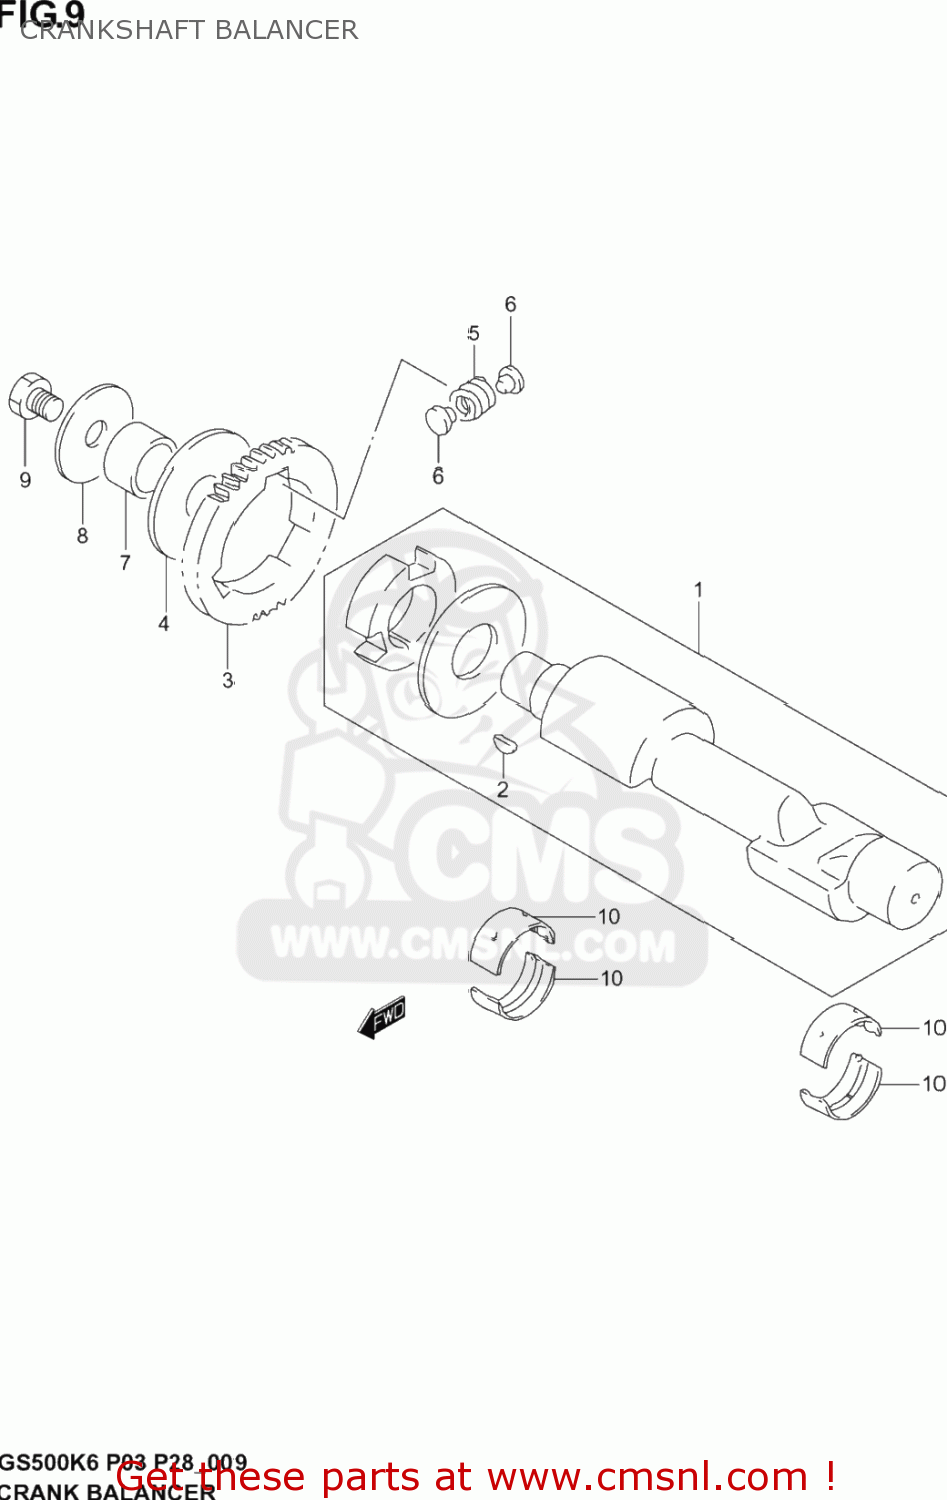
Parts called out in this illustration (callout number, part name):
1	BALANCER,CRANK
2	KEY
3	RACE,CRK BAL DRIVEN GEAR INNER
4	WASHER(24X70X3)
5	SPRING
6	PIN
7	SPACER(24X30.5X12.5)
8	WASHER(12X50X3)
9	BOLT
10	BEARING,CRANKSHAFT(GREEN)
